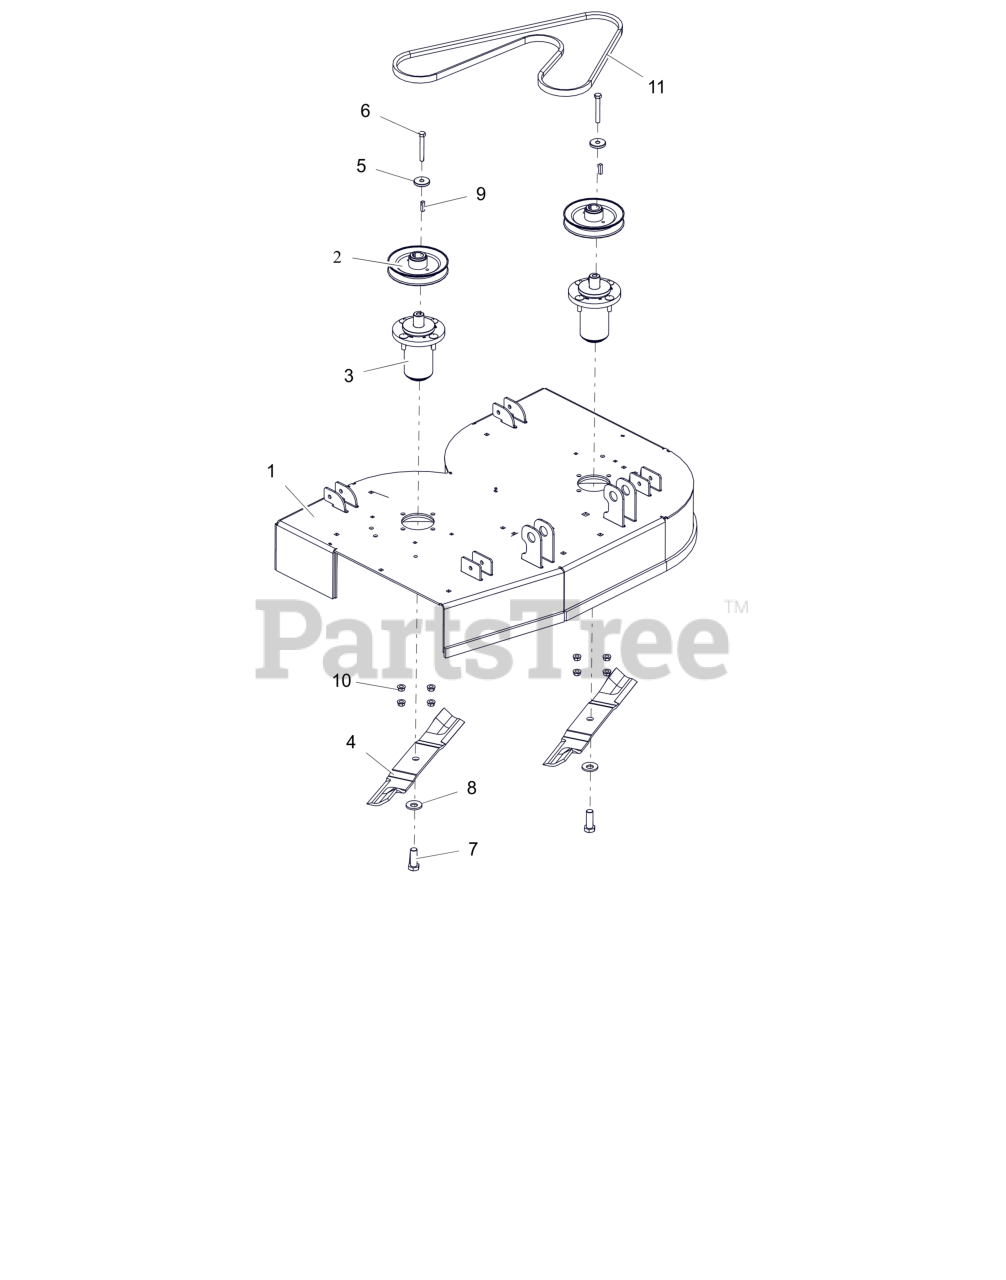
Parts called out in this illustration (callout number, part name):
1	WLDMT, 36" PRO STANCE DECK (RED)
2	PULLEY, V - 1.000 ID X 5.750 OD
3	ASM, MAINT FREE ALUM SPINDLE
4	BLADE, 18.00" MOWER (HI-LIFT)
5	RETAINER, SHEAVE
6	BLT, HEX .38-16X2.75 G8 ZCC
7	BLT, HEX .62-18X1.75 G8 ZCC
8	WSHR-BLVL .669X1.535X.138
9	KEY, SQ .25X.25X1.00 RC 40-50
10	NUT-LK-CTR-FLG .375-16 GF ZCC
11	V-BELT, 5L RAW EDGE EPDM
